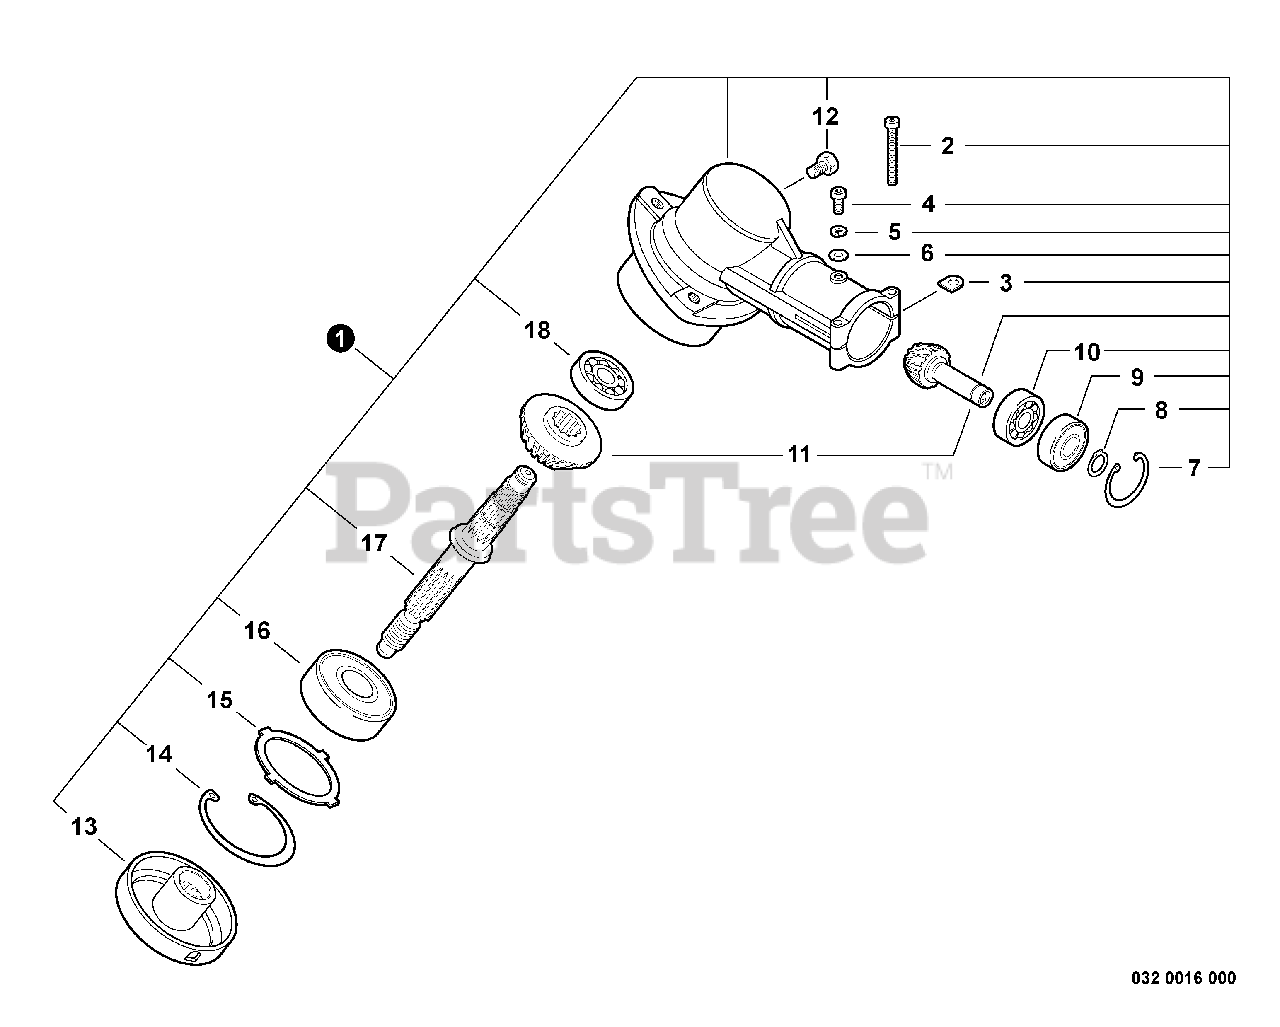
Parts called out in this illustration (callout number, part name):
1	GEAR CASE ASSY
2	BOLT, TORX 5×25
4	BOLT, TORX 5×10
5	WASHER, SPRING 5
6	WASHER, FLAT 5.5×10×0.8
7	RING, SNAP Ø22
8	RING, SNAP Ø10
9	BEARING, BALL 6900Z
10	BEARING, BALL 6900
11	GEAR SET
12	BOLT M8×8
13	PLATE, ADAPTOR - UPPER
14	RING, SNAP Ø32
16	BEARING, BALL 6201
17	SHAFT, GEAR
18	BEARING, BALL 609
